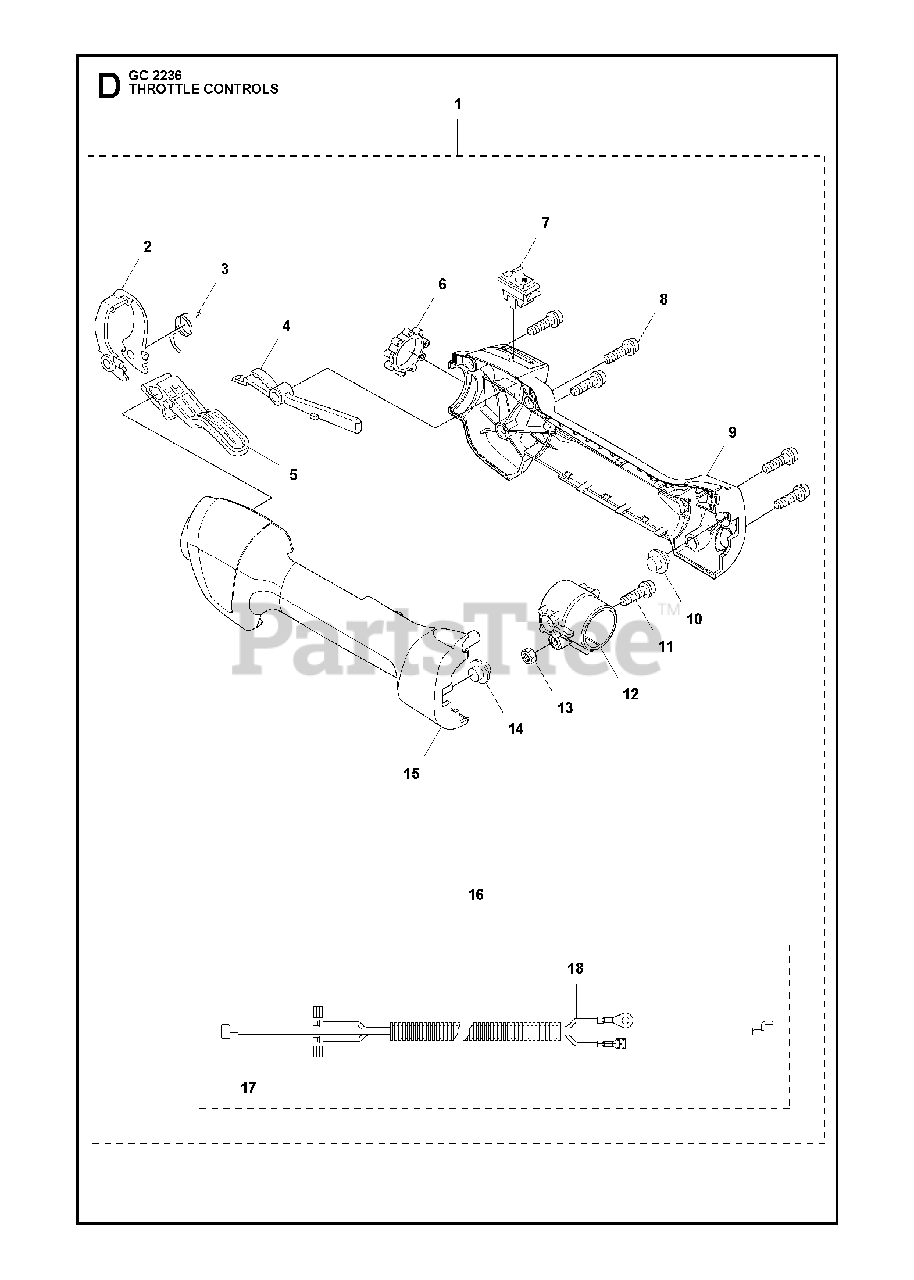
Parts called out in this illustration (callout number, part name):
2	LEVER
3	RETURN SPRING
4	THROTTLE LOCK
5	THROTTLE TRIGGER
6	VIBRATION DAMPER
7	STOP BUTTON
8	SCREW
9	HANDLE HALF
10	VIBRATION ABSORBER
11	SCREW
12	HOLDER
13	NUT
14	VIBRATION ABSORBER
15	HANDLE HALF
16	WIRING ASSY.
17	THROTTLE WIRE ASSY
18	SHORT CIRCUIT CABLE
